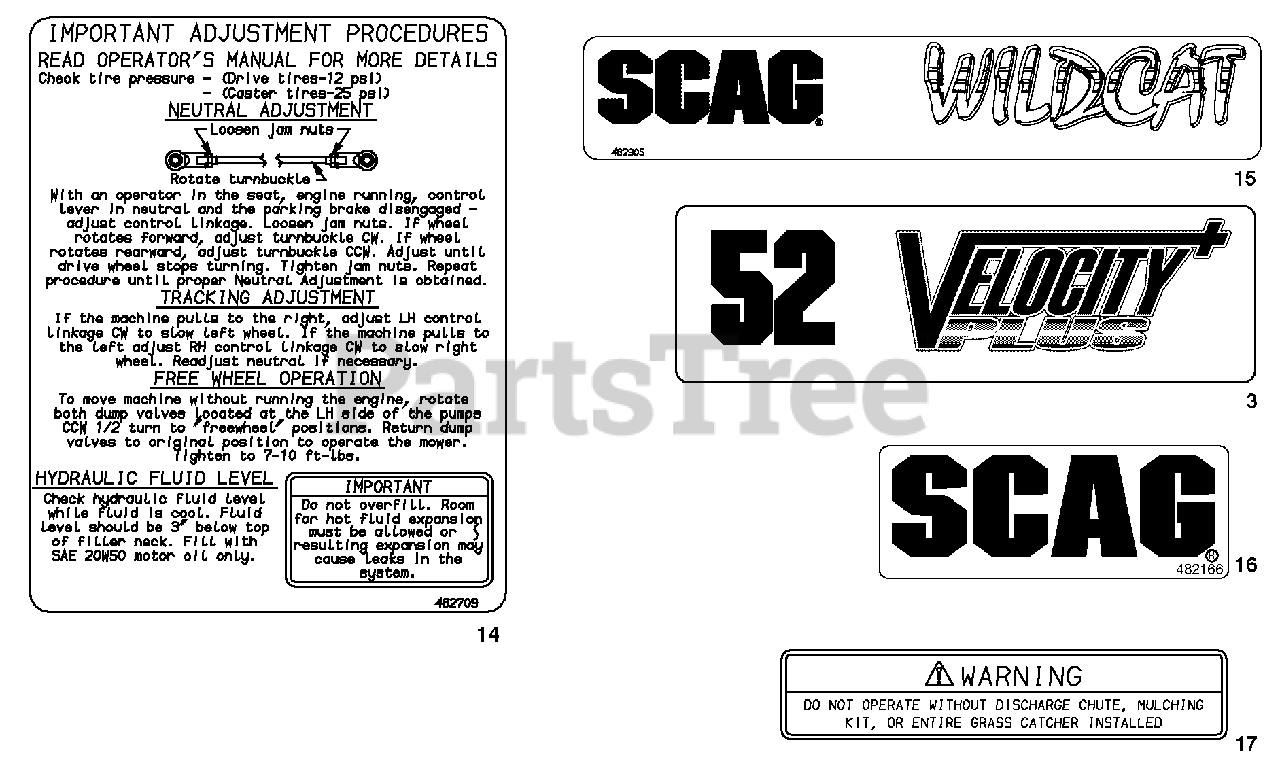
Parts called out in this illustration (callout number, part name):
3	Decal, 48V
14	Decal, 52V
15	Decal, 61V
16	Decal, Front Footplate
17	Decal, Discharge Chute
